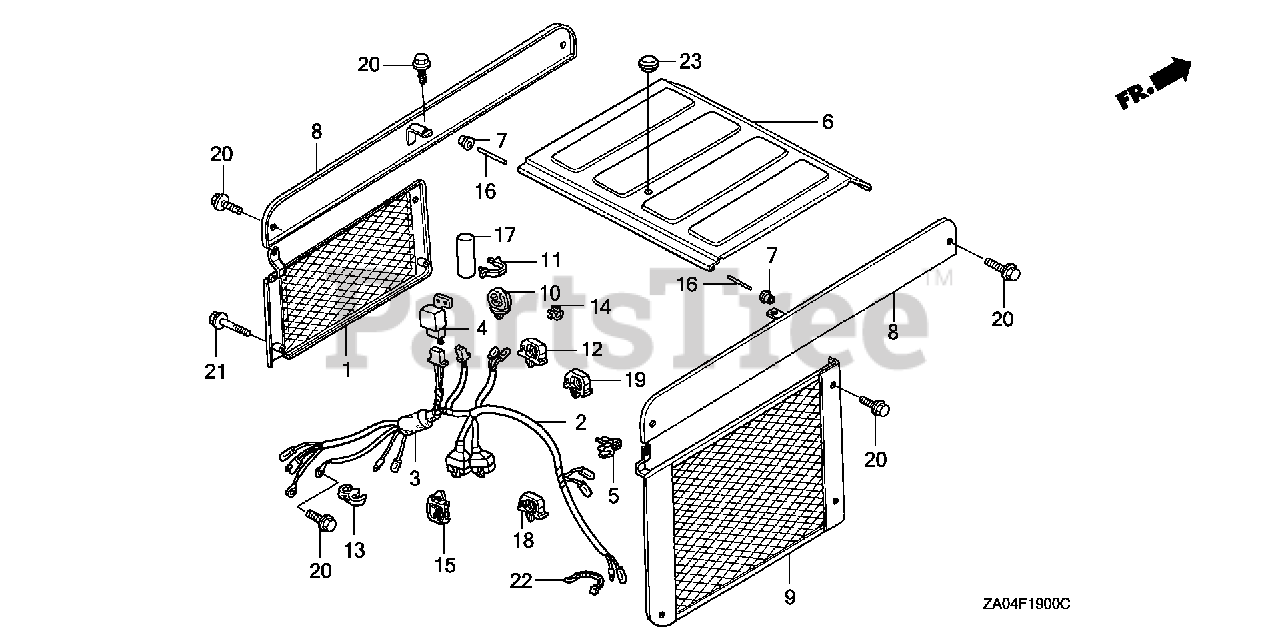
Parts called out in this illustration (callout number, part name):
1	COVER, MUFFLER *NH105* (MAT BLACK)
2	WIRE HARNESS
3	COVER, WIRE HARNESS CONNECTOR
6	COVER, TOP *R280* (POWER RED)
7	BUSH, TOP COVER
8	COVER (UPPER) *R280* (POWER RED)
9	COVER, RADIATOR *NH105* (MAT BLACK)
16	PIN, TOP COVER HINGE
20	BOLT, FLANGE (6X12)
21	BOLT, FLANGE (6X28)
23	GROMMET, WASHER HOLE
